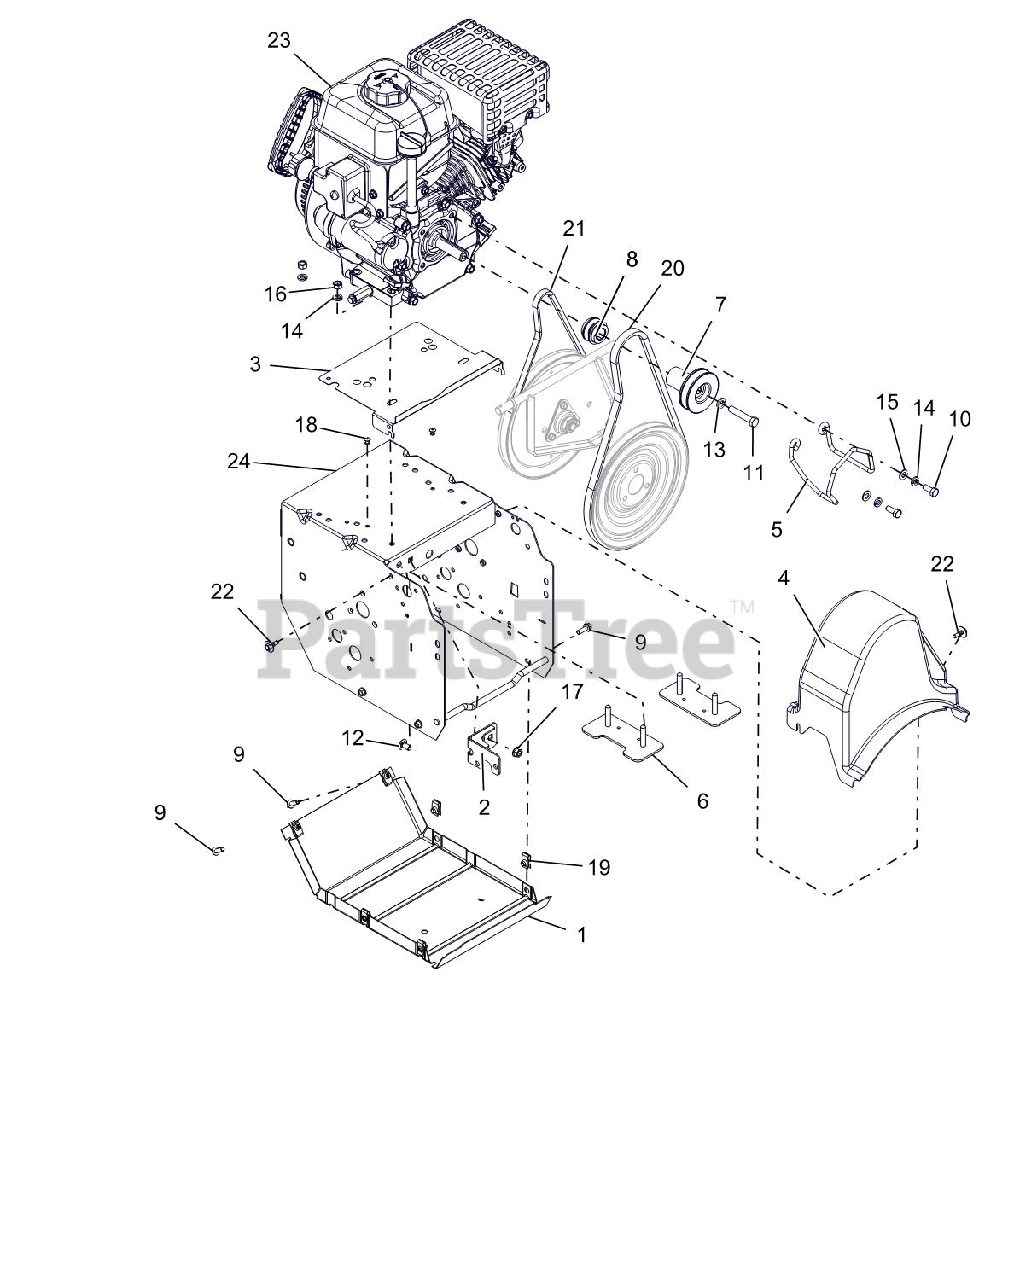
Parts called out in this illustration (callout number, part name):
1	COVER, BOTTOM
2	WELDMENT, FRAME BRACKET
3	BAFFLE, COMPACT
4	COVER, COMPACT BELT
5	FINGER, BELT
6	STRAP, ENGINE BOLT-WELDMENT
7	SHEAVE, AUGER 3/4 - PM
8	TRACTION SHEAVE HALF
9	BLT-HEX .25-20X.75 HWH YZ GR5
10	BLT-HEX .31-24X.75 YWZC GR5
11	BLT-HEX .38-24X2.0 YWZC
12	@BLT-RHDSSQNK .31-18X.62 G5YZ
13	WSHR-LK .375X.115 HVY YWZC
14	WSHR-LK .312X.097 HVY YWZC
15	@WSHR-FL-STL.344X.688X.065YWZC
16	@NUT-HEX .31-18 YWZC
17	@NUT-LK-TOP-FLG .31-18 YWZC
18	RVT-POP .187 YZ
19	NUT-RTNR .25-20X.56
20	V-BELT, HA-RAW EDGE
21	V-BELT, 3L-WRAPPED
22	SCR-TAP .25-20X.5 CAPTIVE
23	ENGINE, SNO-TEK 208 240V
24	FRAME W/ENGINE BOLT STRAPS
